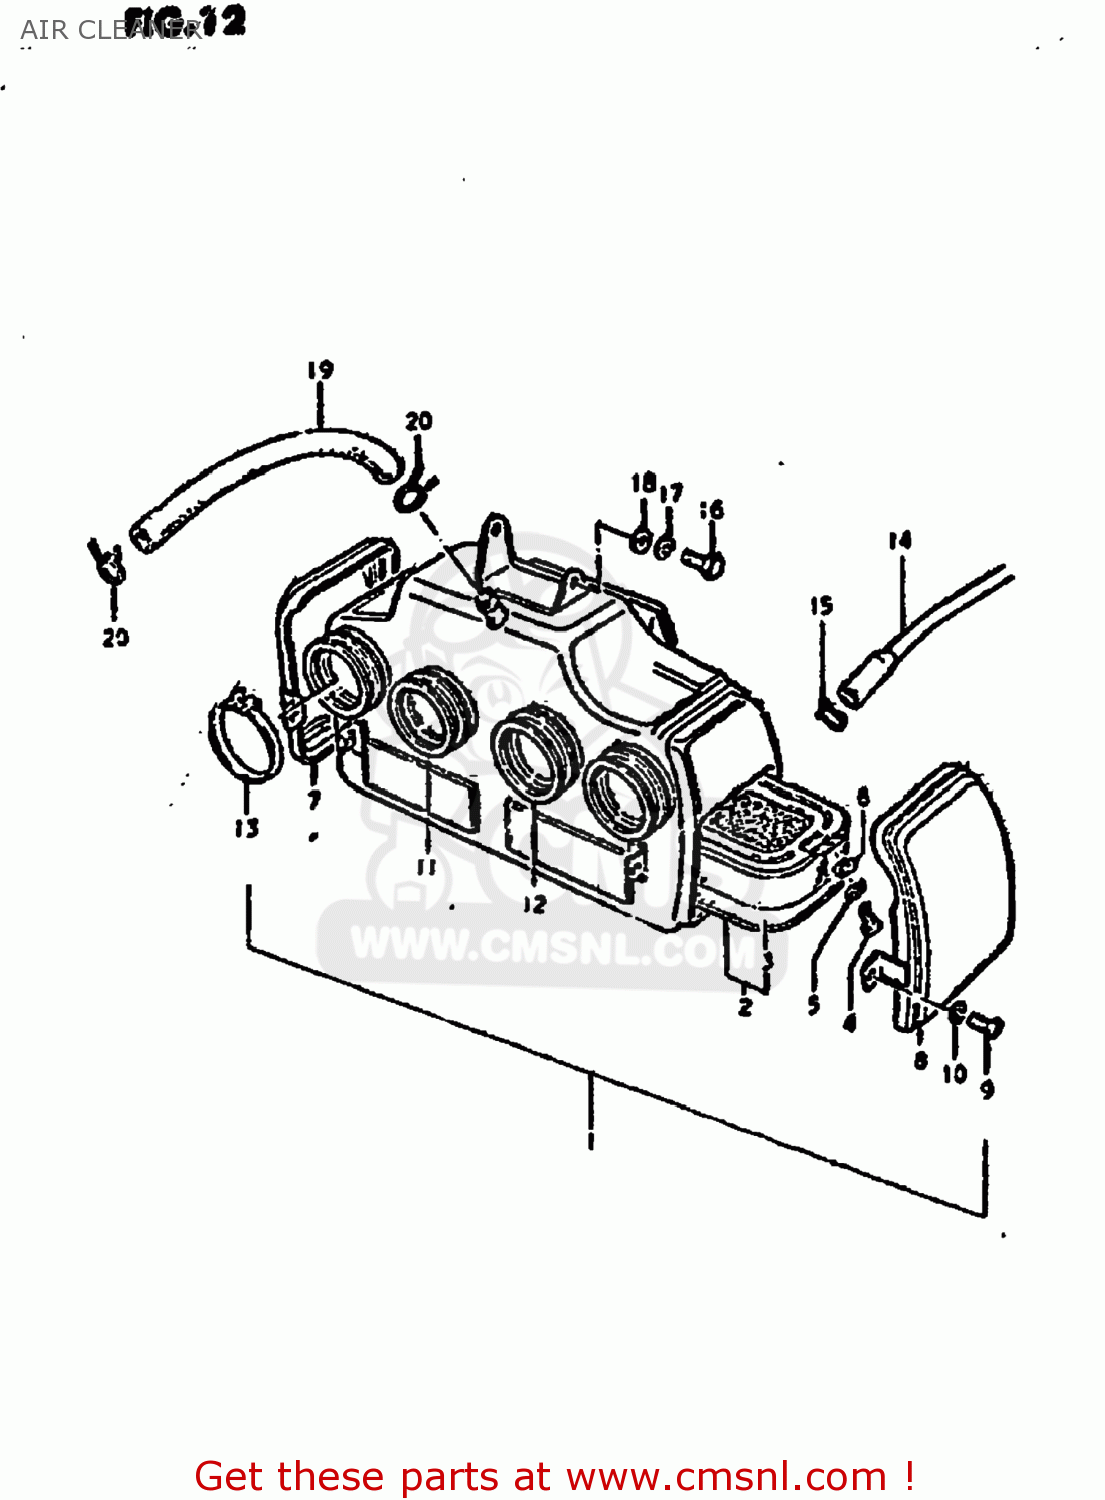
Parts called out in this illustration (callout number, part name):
1	CLEANER ASSEMBLY,AIR
2	FILTER ASSY,AIR CLEANER
3	FILTER
4	SCREW
5	LOCK WASHER
6	WASHER
7	CAP,AIR CLEANER,RIGHT
8	COVER, LH
9	SCREW
10	WASHER
11	HOSE,R
12	HOSE,L
13	CLAMP
14	14-2
15	16
16	BOLT
17	LOCK WASHER
18	WASHER 6MM
19	HOSE
20	CLIP
